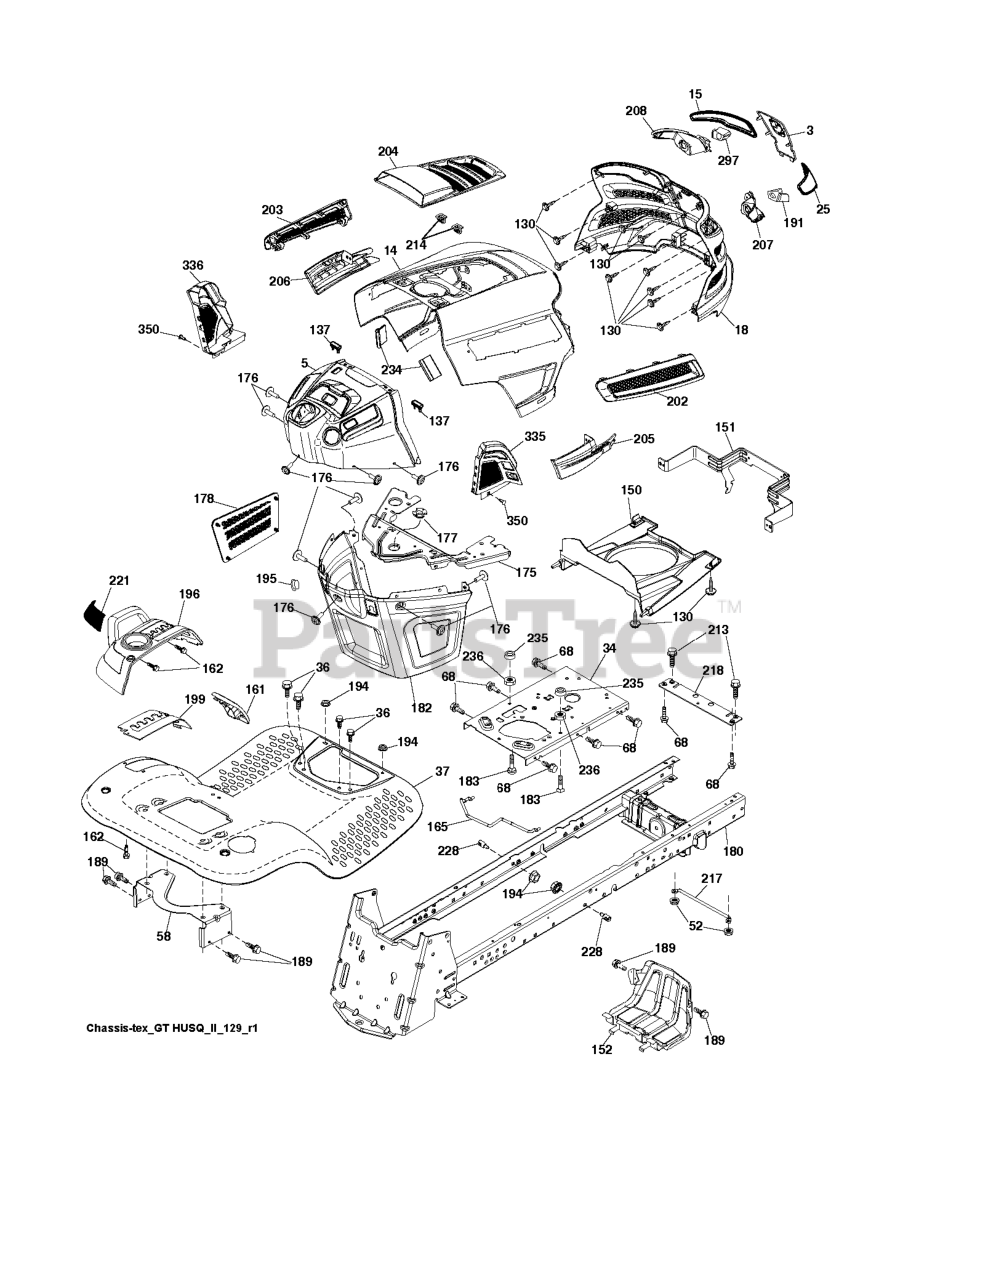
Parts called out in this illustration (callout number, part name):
3	APPLIQUE.SUBASM.GT.HUSQ.II
5	DASH.UPP.GT2.SM.PTO.MCHOKE
14	HOOD.ASM.HUSQVARNA.GT.TEX.ORAN
15	LENS.HEADLIGHT.LH.GTII.2011
18	GRILLE.SUBASM.GT.HUSQ.II
25	LENS.HEADLIGHT.RH.GTII.2011
34	PLATE.ENGINE.WELDED.CHASSIS
36	SCREW 5/16"
37	FENDER.PNT.TX.GT.CH/FW.ORANGE
52	LOCKNUT
58	BRKT.SUPPORT.FNDR/TANK
68	Screw 5/16-18 x 1/2 Hex, Self Tapping 5/16-18 x 1/2
130	SCREW.#10 X 0.750.BOS
137	BUMPER DASH
150	AIR.DUCT.GTV2(2.54"RING HEIGHT
151	BRACKET.PIVOT.HOOD.GT.HUSQ.II
152	SHIELD.BROWNING.PNT.GT.V2
161	CONSOLE.WINDOW.FUEL.HUSQ.GT
162	SCREW.HI-LO.CONSOLE
165	SUPPORT.TANK.REAR.W/TEX
175	PLATE.CROSSMEMBER.HUSQ
176	SCREW.#10-24X5/8.RN.QU
177	BUSHING, STEERING
178	CARGO.ASM.NET.TXGT.W/C
180	CHASSIS.GT.SLOPED.DRAWBAR.
182	DASH.LOWER.COMMON.12V.ADAPTOR
183	BOLT.5/16-18X1-1/4 FULL THD
189	SCREW
191	INSERT.REFLECTIVE.RH.HUSQ.GTII
194	NUT LOCK HEX FLANGE 5/16-18
195	PLUG.HOLE.DASH.LOWER.12V.BLK
196	RP CONSOLE.ASM.DECKLFT.W/
199	PLATE.DECK.LIFT.HUSQVARNA.GT
202	VENT.SIDE.RH.GT.HUSQ.II.
203	VENT.SIDE.LH.GT.HUSQ.II.498
204	VENT.TOP.HUSQ.GT2
205	SIDE.TRIM.RH.GT.HUSQ.II
206	SIDE.TRIM.LH.GT.HUSQ.II.GRAY
207	BEZEL LIGHT.RH.GT.II.MYLAR
208	BEZEL LIGHT.LH.GT.II.MYLAR
213	BOLT
214	CLIP.RETAINER.TINNER.
217	ROD.PIVOT.HOOD
218	X-PIECE.HOOD.STOP.NON/
221	REFLECTOR.LH.TEX GT HU
228	STUD.FASTNER.W/ANTI-ROTATE
234	BUMPER.HOOD.TEX.HUSQVARNA
235	SPACER FENDER
236	NUT.CENTERLOCK.5/16-
297	INSERT.REFLECTIVE.LH.HUSQ.GTII
335	COVER.LOWER.DASH.RH.BLACK
336	COVER-LH.LOWER.DASH.GT2.BLACK
350	CLIP.X-MAS.TREE
